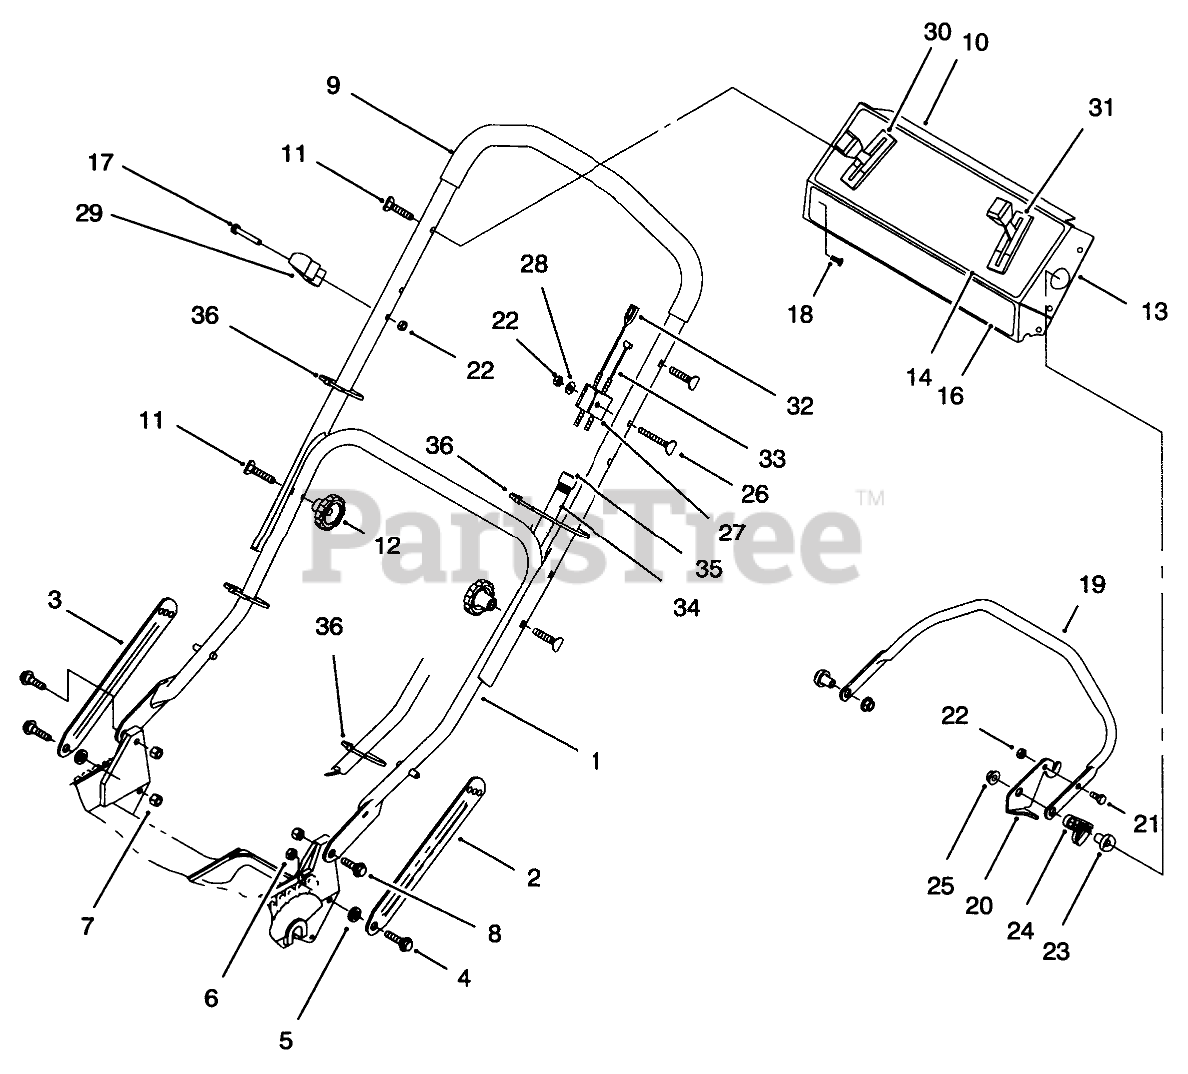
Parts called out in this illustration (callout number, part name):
1	ASM-Handle
2	Latch-Handle
3	Latch-Handle
4	SCREW-SHOULDER
5	SPACER
6	NUT-LOCK, NI
7	NUT-LOCK, NI
8	SCREW-SHOULDER
9	HANDLE - DIPPED
10	DECAL-PANEL, REAR
11	SCREW-HANDLE
13	Panel-Control (Incl. Ref. #10, 14)
14	DECAL - INSTRUCTION
16	DECAL - PANEL (TORO)
17	.250-20X1.625 HH SCREW
18	SCREW-TAP
19	BAR-CONTROL
20	Lever-Control
21	SCREW-HH
22	NUT-LOCK, NI
23	SPACER-SUPPORT
24	LEVER-TRACTION
25	NUT-LOCK NI
26	SCREW-HANDLE
27	SUPPORT-CABLE
28	WASHER-FLAT
29	GUIDE-ROPE
30	CONTROL-SPEED, GROUND
31	THROTTLE CONTROL
32	BRAKE CONTROL
33	CABLE-TRACTION
34	CONTROL CABLE COVER
35	FITTING-RING
36	TIE-CABLE
